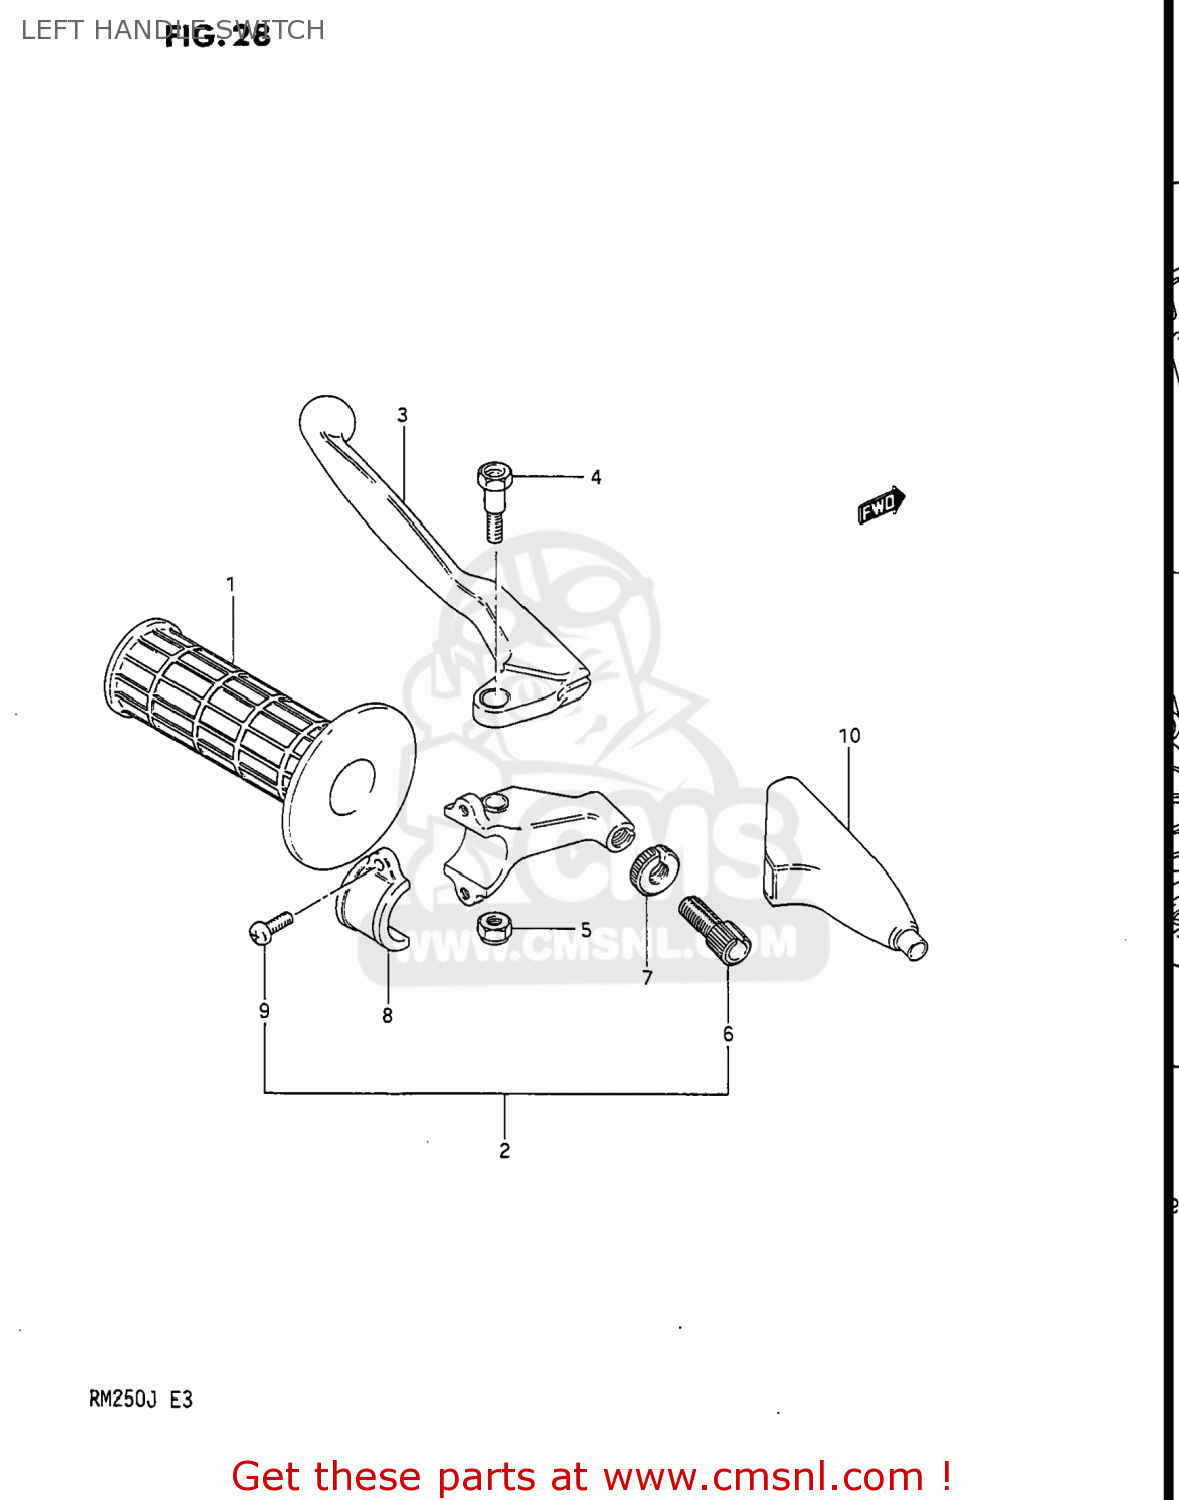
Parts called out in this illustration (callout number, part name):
1	GRIP,LEFT
2	LEVER ASSEMBLY
3	LEVER,CLUTCH
4	BOLT,LEVER
5	NUT
6	ADJUSTER,CABLE
7	NUT,CABLE ADJUSTER LOCK
8	HOLDER,LEVER
9	SCREW (5X14)
10	COVER,CLUTCH LEVER
